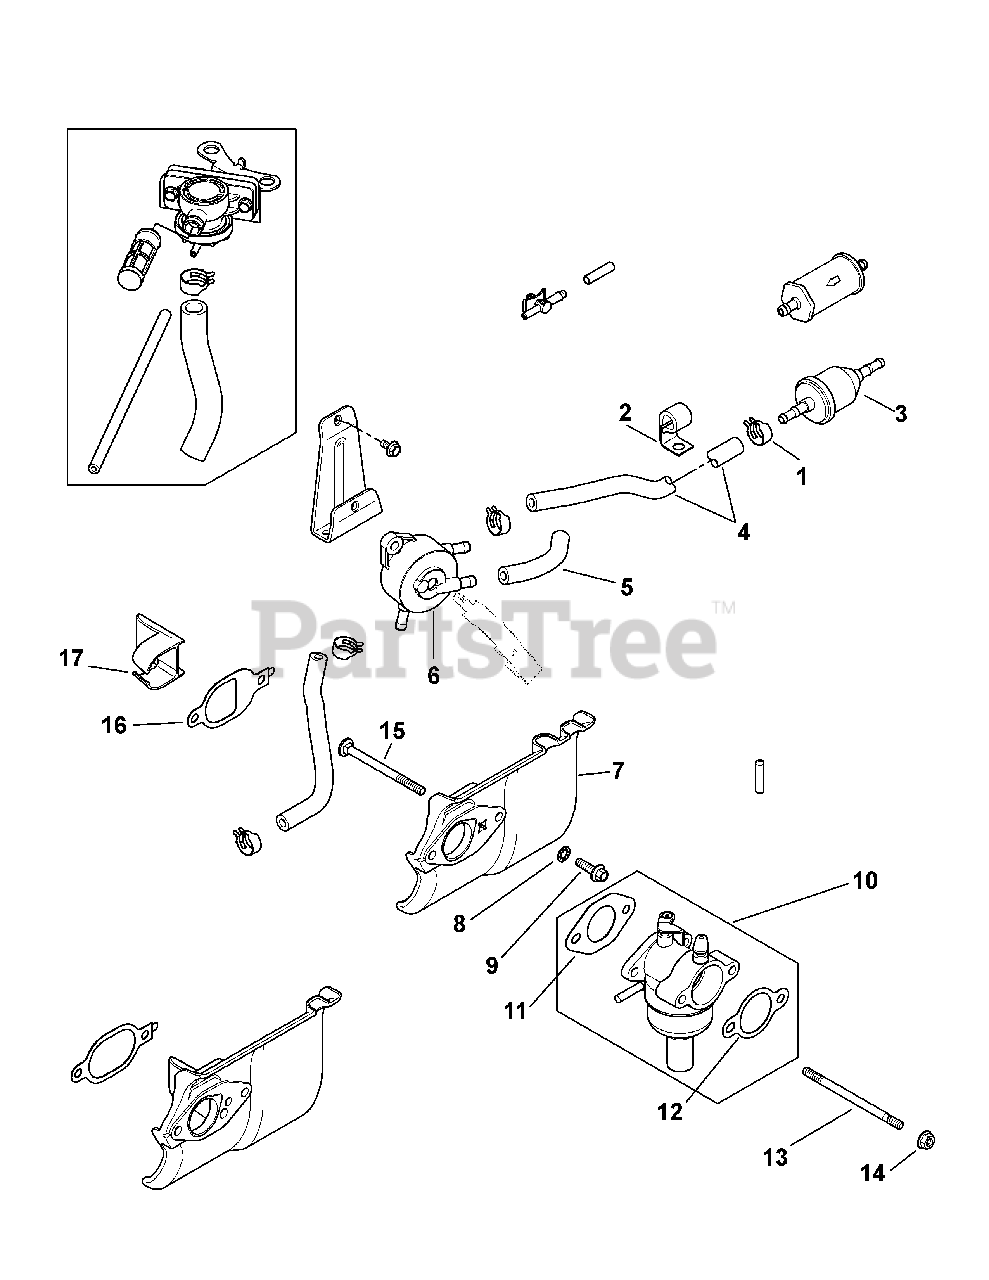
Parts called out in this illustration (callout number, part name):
1	Hose Clamp, 1.2
3	Fuel Filter
4	Fuel Line, 24
7	Heat Deflector Kit (Inc. 12, 15-17)
8	Internal Tooth Lock Washer, 1.4
9	Flange Screw, M6 x 1.0 x 20
10	Carburetor Service Kit (Inc. 11 & 12)
11	Carburetor Gasket
12	Air Cleaner Base Gasket
13	Stud, M6 x 1.0 x 100
14	Flange Nut, M6 x 1.0
15	Carburetor Stud
16	Heat Deflector Gasket
17	Intake Port Insert
